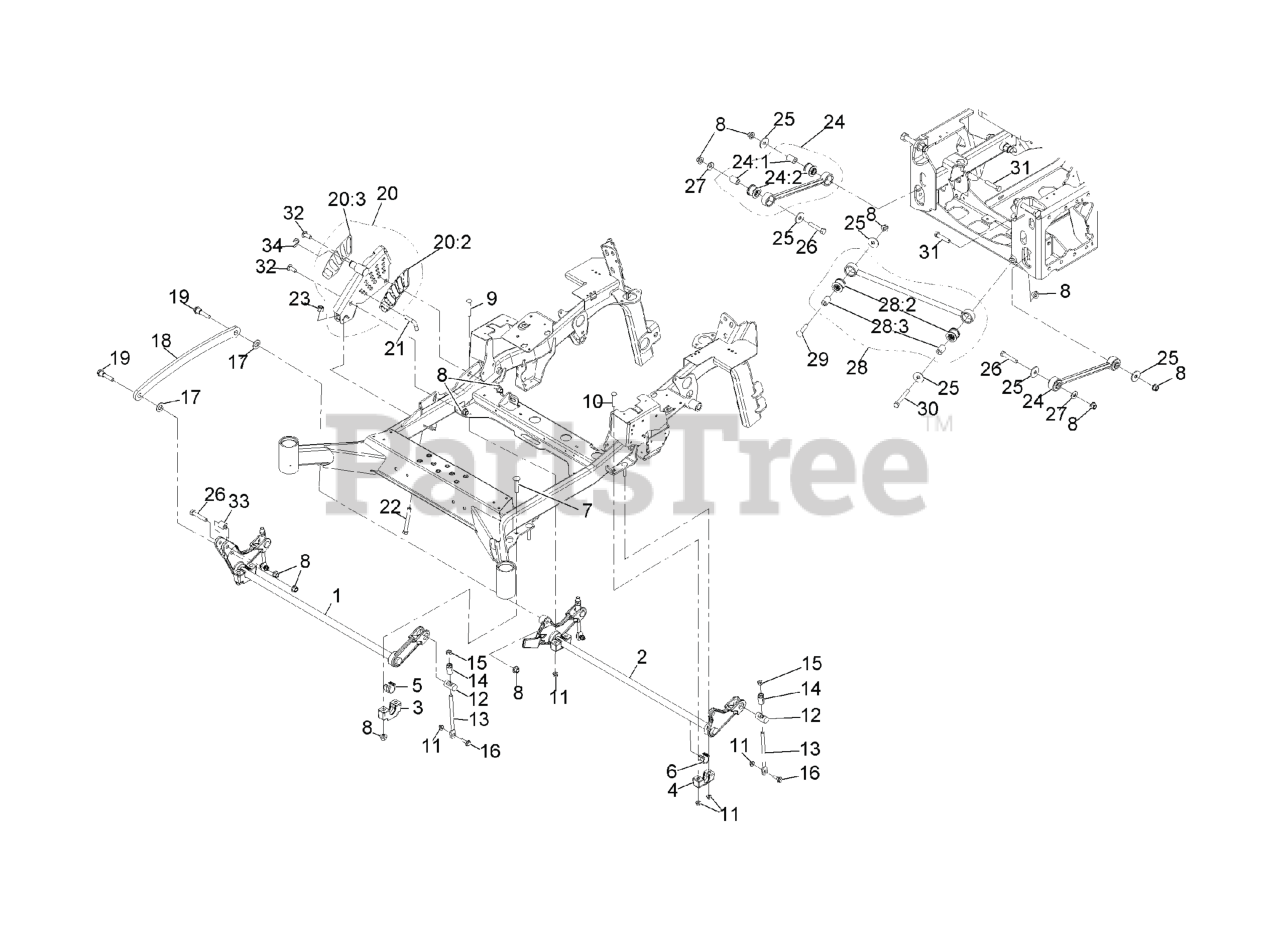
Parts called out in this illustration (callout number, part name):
1	DECKLIFT-FRONT
2	LIFT-DECK, REAR
3	SUPPORT-CROSS SHAFT, BEARING
4	SUPPORT-CROSS SHAFT, BEARING REAR
5	BEARING-CROSS SHAFT, FRON
6	BEARING-CROSS SHAFT, REAR
7	Bolt-Carriage 1/2-13 X 2 1/2 Spl Neck
8	Nut-Lock 1/2-13
9	SCREW-CARR
10	Bolt-Carriage 3/8-16 X 2 1/4
11	NUT-HF, NI
12	TRUNNION
13	LINK-ADJUSTER, DECK LIFT
14	ADJUSTER-LIFT, DECK
15	NUT-JAM
16	SCREW-SHOULDER, HHF
17	WASHER-FLAT
18	LINK-LIFT, DECK
19	SCREW-HHF, SHOULDER
20	HOC ASM
20:2	DECAL-HEIGHT OF CUT
20:3	DECAL-HEIGHT OF CUT, OUTER
21	PIN-HOC
22	BOLT-TAP
23	NUT-LOCK, NI
24	DECK STRUT ASM 85A
24:2	BUSHING-RUBBER
25	WASHER-THRUST
26	SCREW-HH
27	WASHER-SPRING
28	PANHARD ROD ASM
28:2	BUSHING-SUSPENSION, RUBBER
29	SCREW-CARR
30	SCREW-HH
31	SCREW-HH
32	SCREW-CARR, SHORT NECK
33	SPACER-PIVOT
34	RING-RETAINING
